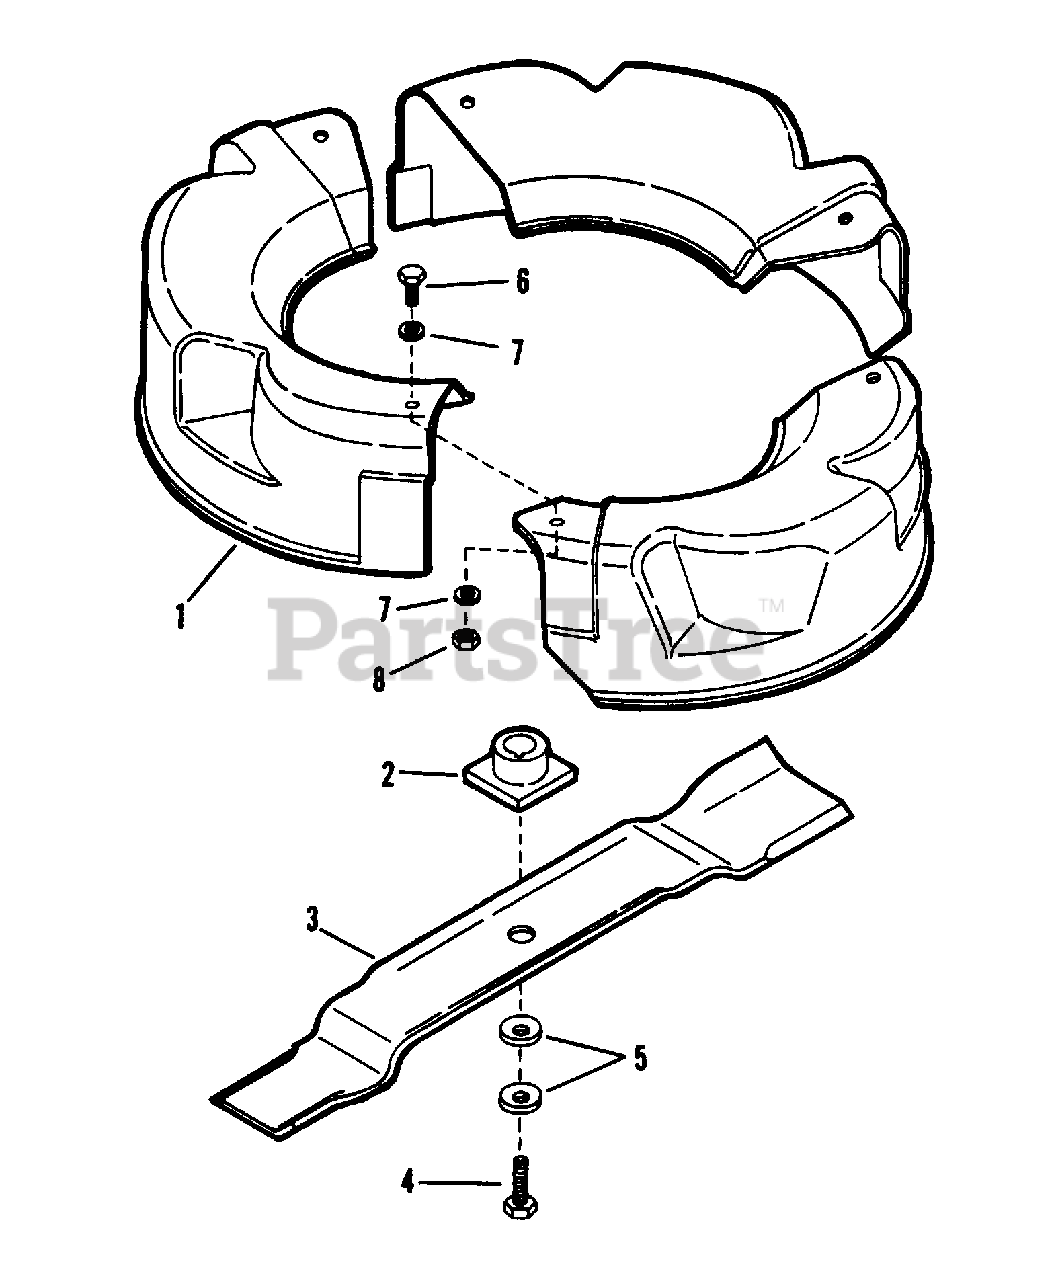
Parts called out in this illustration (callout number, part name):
2	HUB, 7/8" I.D.
3	BLADE, Mulcherizer
4	SCREW, 3/8-24 x 1-3/4" Hex Head Cap, Grade 5
5	WASHER, Cone
6	SCREW, 1/4-28 x 5/8" Hex Head Cap, Grade 5
7	WASHER, 1/4" Flat
8	NUT, 1/4-28 Hex Top Lock
